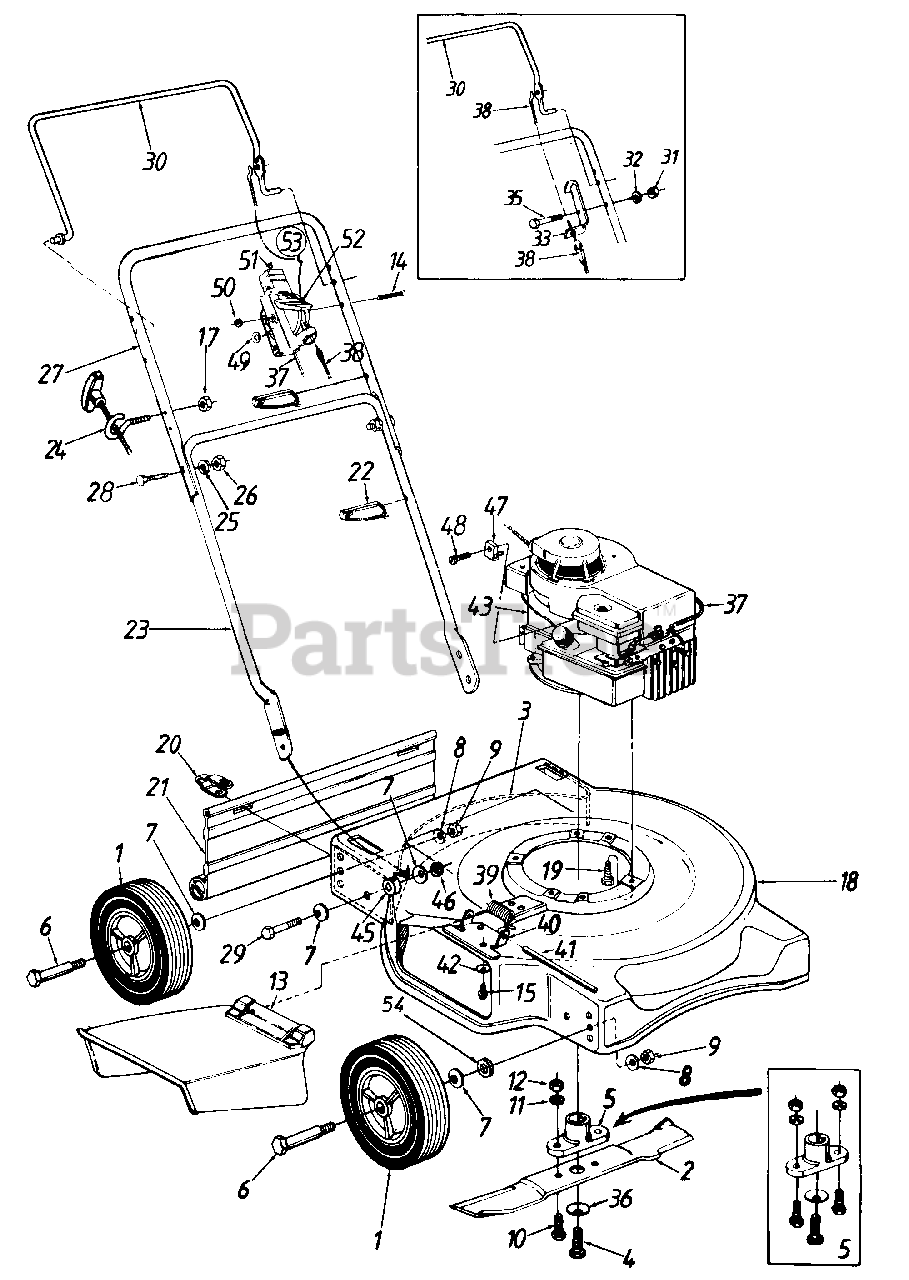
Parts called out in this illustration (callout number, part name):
1	Wheel Ass'y. Complete
2	20" Blade
5	Blade Adapter Kit
6	Axle Bolt
7	Bell-Wash..380" I.D. x .88"
8	Bell-Wash..39" I.D. x 1.13"
9	Hex Nut 3/8-16 Thd.
10	Hex Bolt 3/8-24 x 1" Lg.
11	L-Wash. 3/8" I.D.
12	Hex Nut 3/8-24 Thd.
13	Chute Deflector Ass'y.
14	Oval C-Sunk Scr.
15	Self-Tap Scr. 1/4-20 x .5" Lg.
17	Hex L-Nut 1/4-20 Thd.
20	Hinge Clip
21	Rear Flap 16.62" Lg.
22	Cable Tie
23	Lower Handle
24	Rope Guide
25	L-Wash. 5/16" I.D.
26	Hex Nut 5/16-18 Thd.
29	Hex Bolt 3/8-24 x 1.5" Lg.
31	Hex Nut 1/4-20 Thd.
32	Spr. Wash..265" I.D. x .562"
33	Cable Mounting Bracket
35	Hex Bolt 1/4-20 x 1" Lg.
36	Bell-Wash..39" I.D.
37	Throttle Control Wire 51" (B&S)
38	Control Cable - 36" (B&S)
39	Torsion Spring
40	Adapter Plate
41	Hinge Pin
42	Bell-Wash. 1/4" I.D.
43	Engine
45	Spacer
46	Hex L-Nut 3/8-24 Thd.
47	Casing Clamp (B&S)
48	Hex Wash. Hd. Scr. #10-32 x .62" Lg. (B&S)
49	Spring Wash..66" I.D.
50	Hex L-Nut 1/4-20 Thd.
51	Throttle Body
52	Throttle Lever
53	Throttle Box Comp.
54	Fl-Wash. 3/8" I.D.
